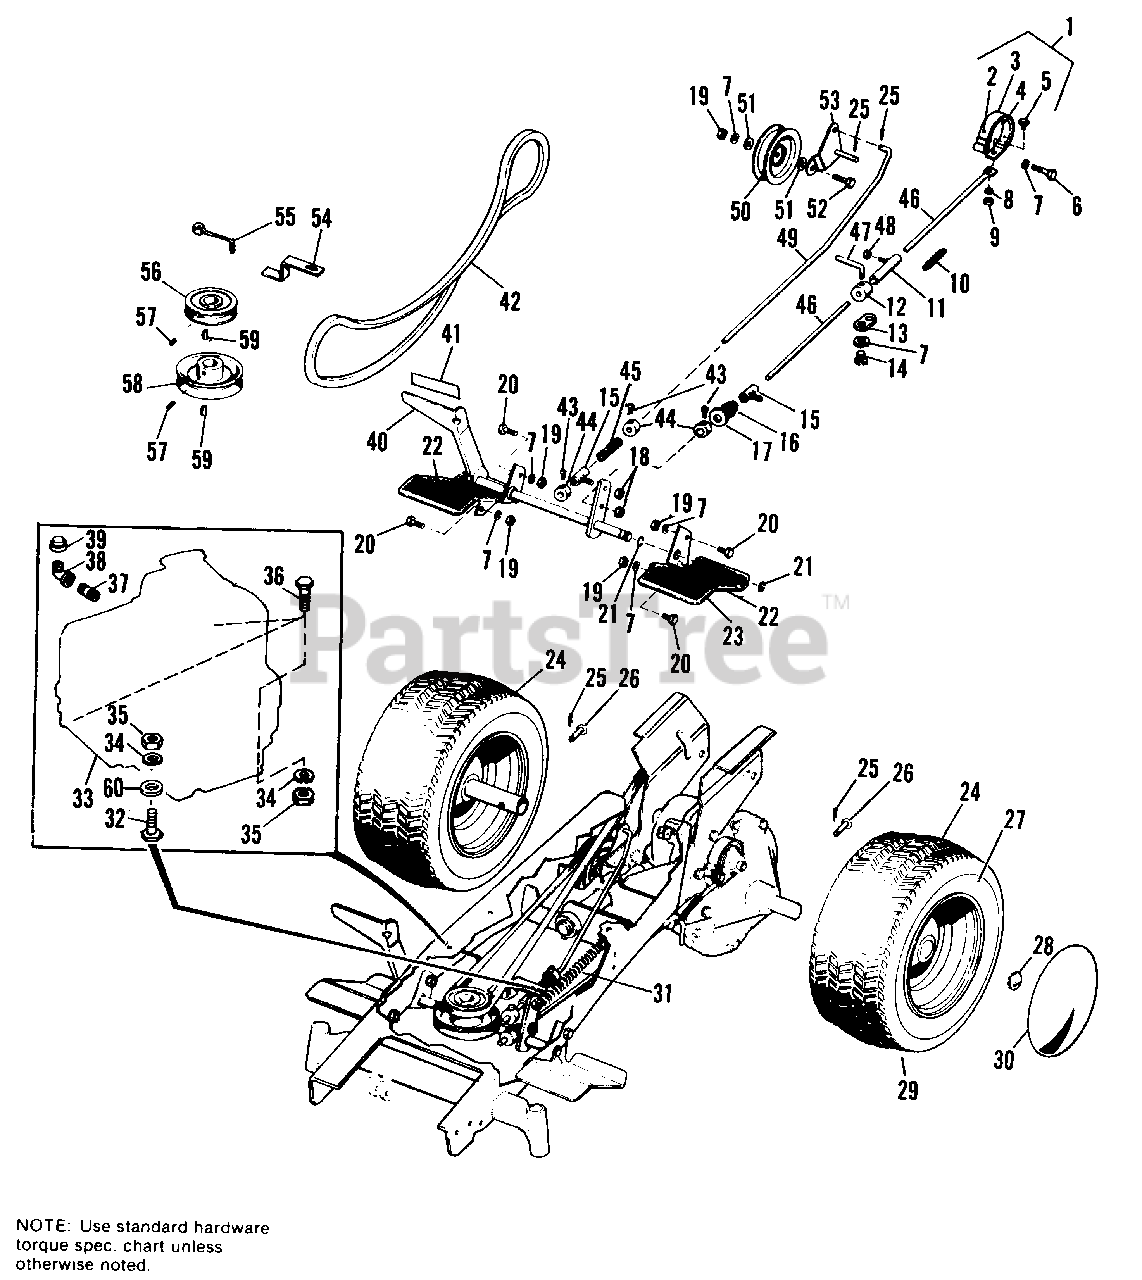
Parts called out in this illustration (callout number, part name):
1	BAND ASSY., Brake
2	RIVET, #7 x 1/4
3	BAND, Brake
4	LINING, Brake
5	CAPSCREW, Hex Hd., 1/4-20 x 3/4
6	CAPSCREW, Hex Hd., 3/8-16 x 1-1/2
7	LOCKWASHER, 3/8
8	LOCKWASHER, 1/4
9	NUT, Hex, Full, 1/4-20
10	SPRING (990645 8 990646 Only)
11	GUIDE ASSY., Rod
11	GUIDE ASSY., Rod (990415, 990597, 990598 Only)
12	COLLAR, Parking Brake
13	ANCHOR, Spring (990645 8 990646 Only)
14	SCREW, Hex, Taptite, 3/8-16 x 1/2 (990645 8 990646 Only)
15	GUIDE ASSY., Rod
16	SPRING (990597, 990598, 990778, 990779 Only)
17	WASHER, Plain, 3/8 (990597, 990598, 990778, 990779 Only)
18	LOCKNUT, Hex, 5/16-18 (Qty. 1 on 990415, 990482, 990542 Only)
18	RING, Snap
19	NUT, Hex, Full, 3/8-16
20	CAPSCREW, Hex Hd., 3/8-16 x 3/4
21	RING, Snap (990645 & 990646 Only)
21	WHEEL & TIRE ASSY., Rear
22	COVER, Footrest
23	FOOTREST, L.H.
24	WHEEL & TIRE ASSY., Rear (990645 & 990646 Only)
25	PIN, Cotter, 1/8 x 3/4
26	PIN
27	WHEEL ASSY.
28	BUTTON, Plug
29	TIRE, Tubeless (990645 & 990646 Only)
29	TIRE, Tubeless
30	CAP, Hub, Rear
31	SPRING, Return
31	SPRING, Return (990415 Only)
32	CAPSCREW, Special (990645 & 990646 Only)
32	CAPSCREW, Hex Hd., 5/16-18 x 1-1/2
34	LOCKWASHER, 5/16
35	NUT, Hex, Full, 5/16-18
36	CAPSCREW, Hex Hd., 5/16-18 x 1-1/2
37	NIPPLE, Pipe, 3/8
38	ELBOW, Street, 45ø
40	SHAFT ASSY., Clutch
41	PAD, Pedal
42	V-BELT, Drive
43	SETSCREW, 1/4-20 x 3/8
44	COLLAR, Set
45	SPRING (990415, 990486 & 990542 Only)
46	ROD, Brake
47	LOCK, Parking Brake
48	LOCKNUT, Hex, 1/4-20
49	ROD, Clutch
50	PULLEY, Idler
51	WASHER, Plain, 5/16
52	CAPSCREW, Hex Hd., 3/8-16 x 1-1/4
53	BRACKET ASSY., Pulley
54	STOP, Belt
55	STOP, Belt
56	PULLEY, Engine, Small
57	SETSCREW, 5/16-18 x 1/2
58	PULLEY, Engine, Large
60	WASHER, Plain, 1/4 (990486, 990542, 990645 & 990646 Only)
